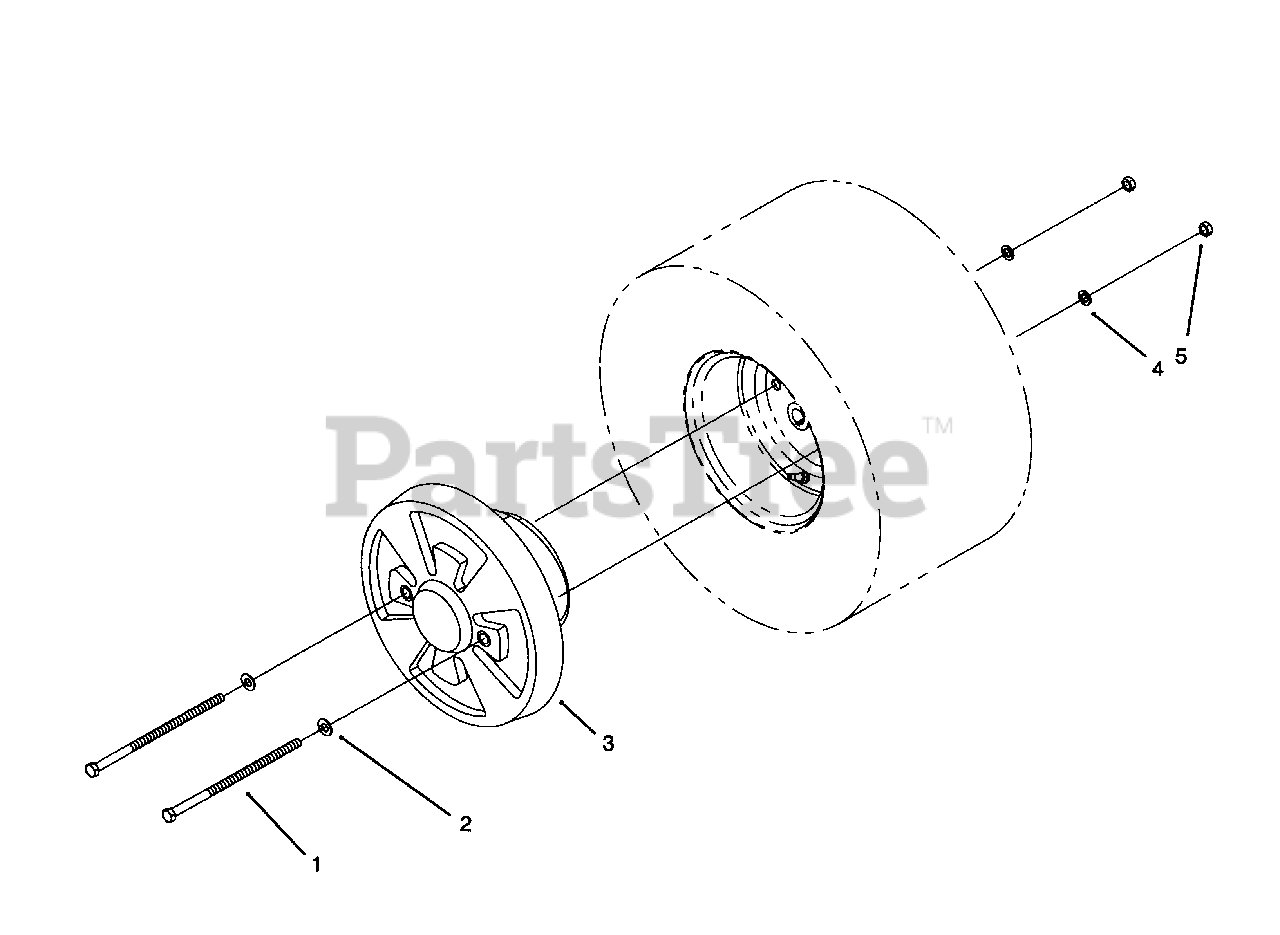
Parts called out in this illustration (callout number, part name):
1	Screw-Hex Hd. Cap
2	Washer-Flat
3	Weight-Wheel
4	Washer-Lock
5	Nut-Hex
